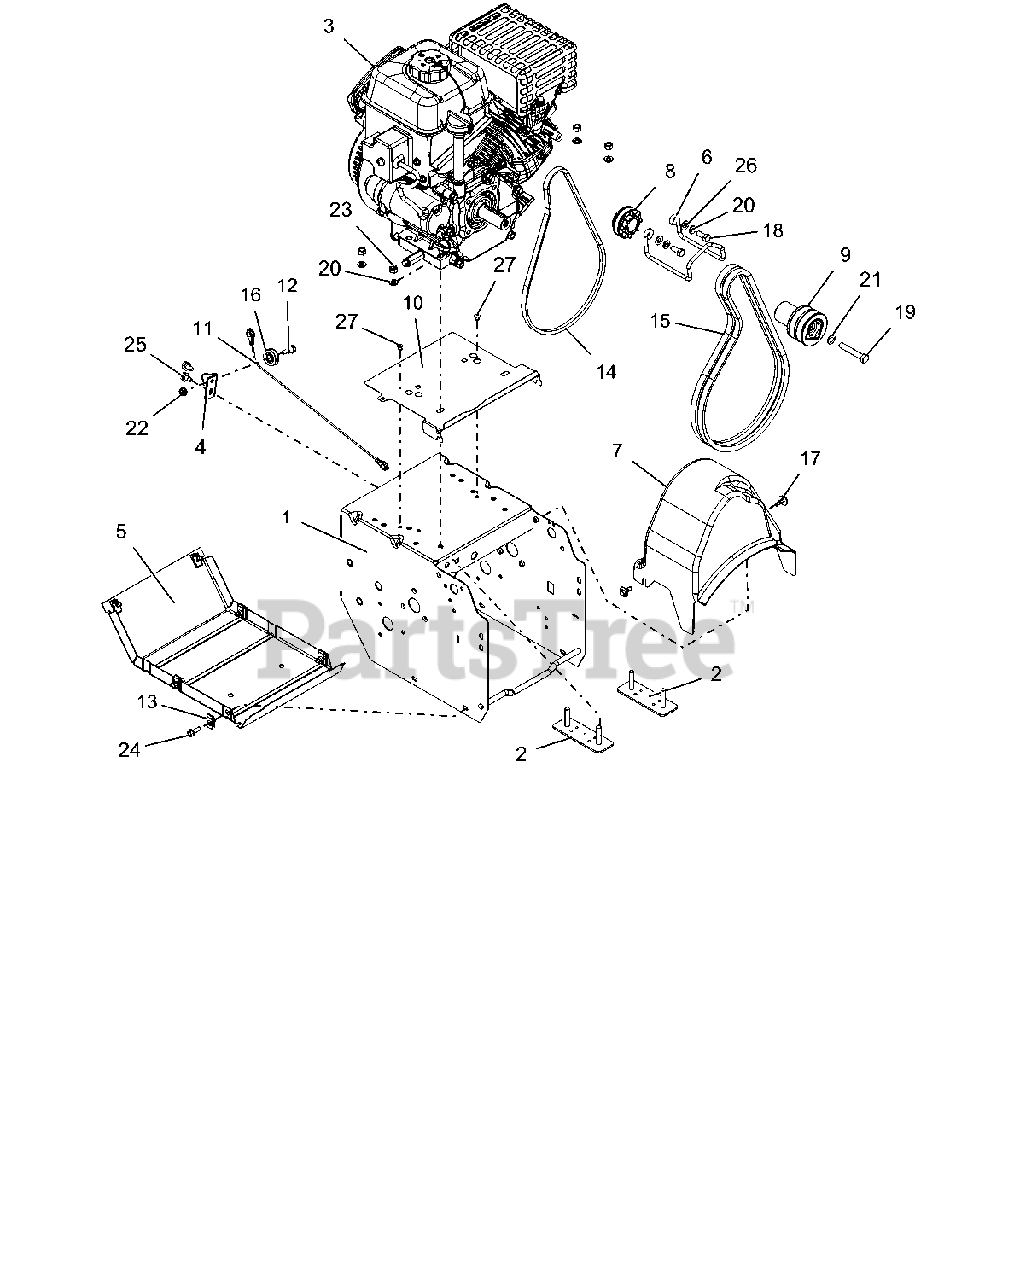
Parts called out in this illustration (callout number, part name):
1	WELDMENT, FRAME - DELUXE 16"
2	STRAP,ENGINE BOLT,ARIENS SML
3	ENGINE, AX254 GEN 2 120V/60W
4	BRACKET, CABLE PULLEY
5	COVER, BOTTOM
6	FINGER, BELT
7	BELT COVER
8	SHEAVE, DRIVE
9	SHEAVE,ATTACHMENT 2-GRV
10	BAFFLE,ENGINE,ARIENS SML BLOCK
11	CABLE, LOWER TRACTION (DELUXE)
12	BOLT, SHLDR-.375X.375X.25-20
13	NUT-RTNR .25-20X.56
14	V-BELT, 3L-WRAPPED
15	V-BELT, HA-RAW EDGE (SET)
16	PULLEY, CABLE
17	SCR-TAP .25-20X.5 CAPTIVE
18	BLT-HEX .31-24X.75 YWZC GR5
19	BLT-HEX .38-24X2.25 YWZC GR5
20	WSHR-LK .312X.097 HVY YWZC
21	@WSHR-LK .38X.094 REG YWZC
22	@NUT-LK-CTR-FLG .25-20 YWZC
23	@NUT-HEX .31-18 YWZC
24	BLT-HEX .25-20X.75 HWH YZ GR5
25	@SCR-TAP .31-18X.50 HWH TR YWZ
26	@WSHR-FL-STL.344X.688X.065YWZC
27	RVT-POP .187 YZ
